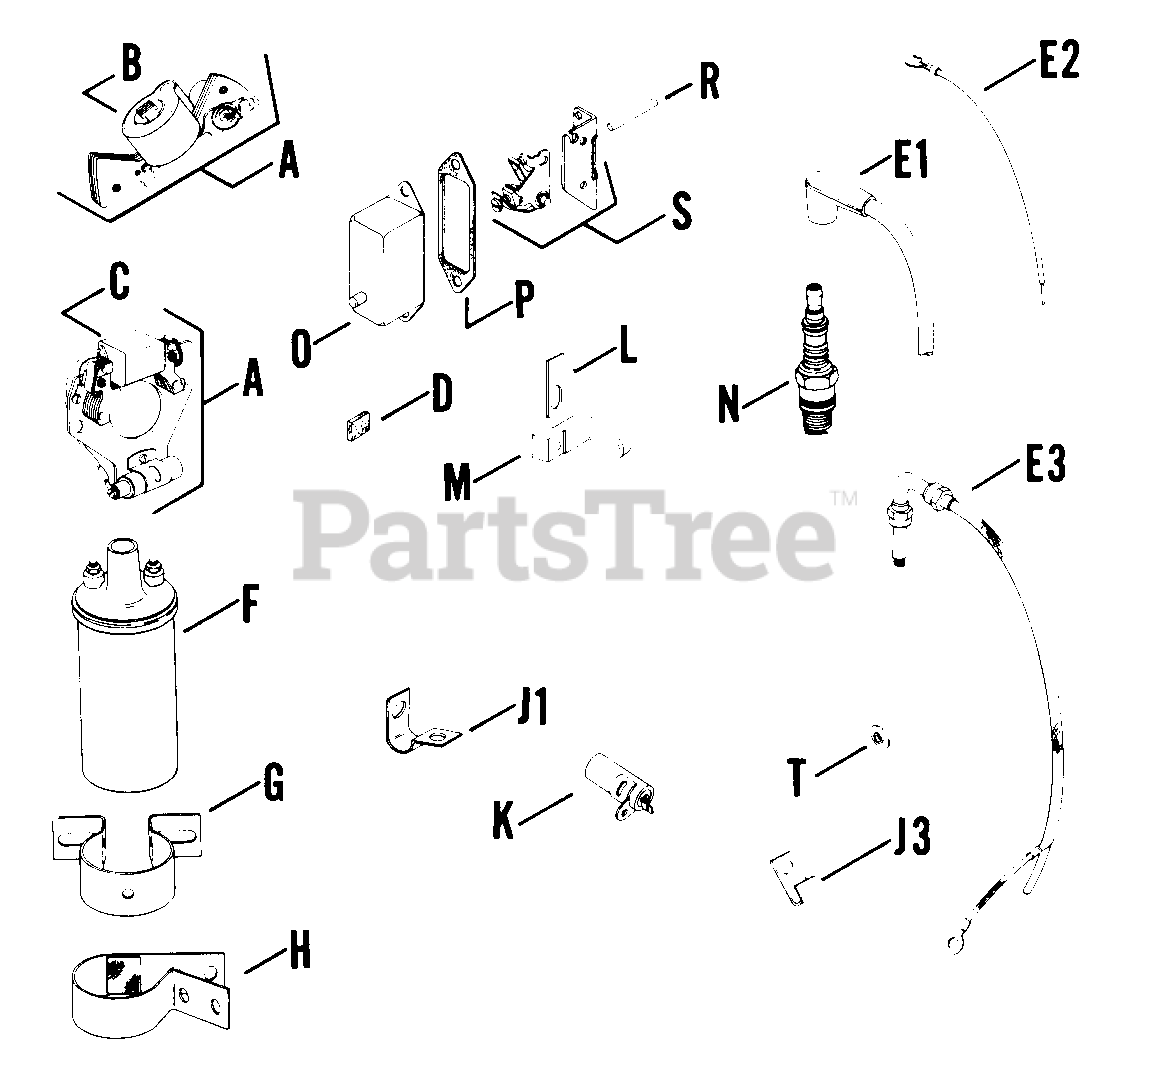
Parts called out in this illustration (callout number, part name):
A	STATOR
B	COIL - DISCONTINUED
E1	LEAD - USE 25 348 01
J1	CLIP - USE 210281
K	CONDENSER - DISCONTINUED
N	SPARK PLUG - USE 41 132 06
O	COVER-(#DSC)
P	GASKET - USE 52 041 11
R	ROD-(#DSC)
S	BREAKER - USE 47 150 03
